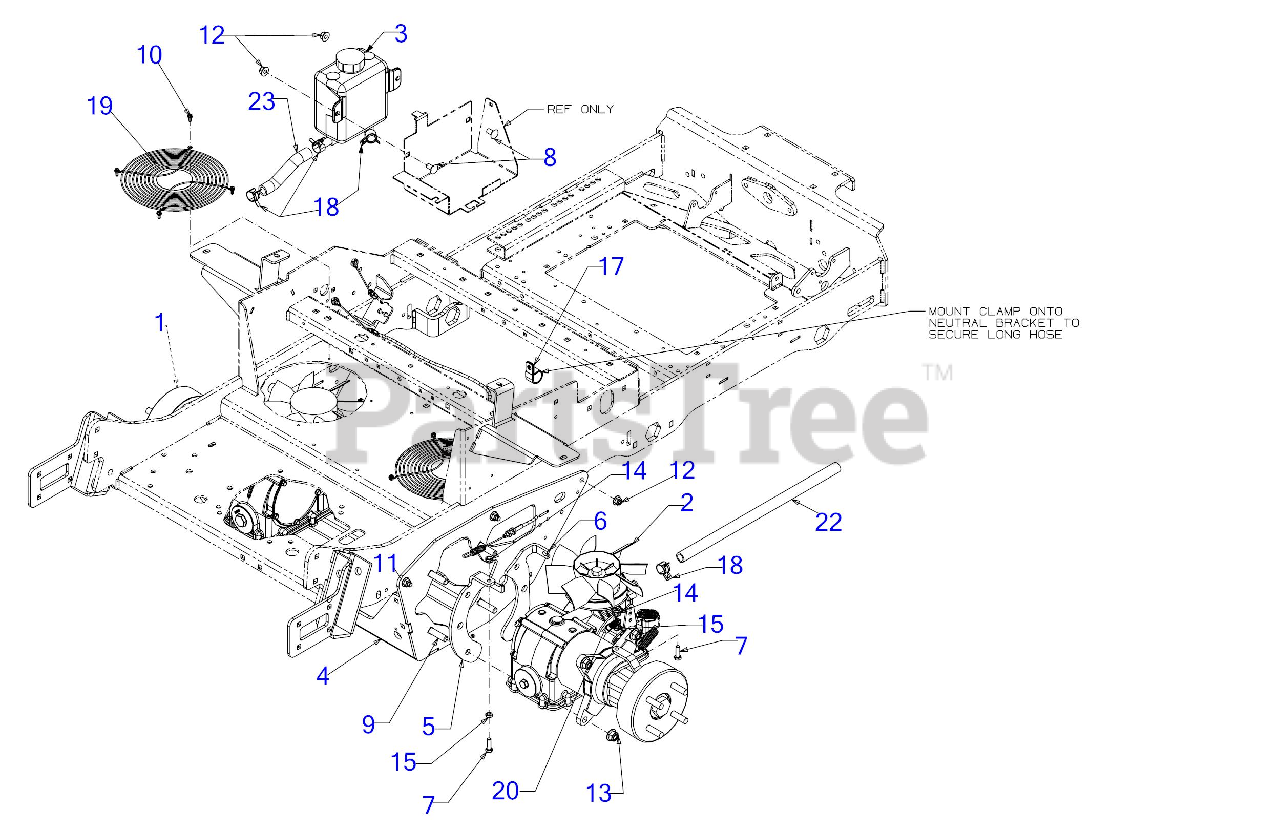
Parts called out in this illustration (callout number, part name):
1	TRANSMISSION/MOTOR ASSEMBLY (LH)(PARKER)
2	TRANSMISSION/MOTOR ASSEMBLY (RH)(PARKER)
3	HYDRO TANK ASSEMBLY
7	SCREW 5/16-18 x 1.0 GR5
8	CARRIAGE BOLT 3/8-16 x .750 GR5
9	CARRIAGE BOLT 1/2-13 GR5
10	SCREW 10-24 x 0.500
11	CARRIAGE BOLT 3/8-16 X1.25 GR5
14	HEX FLANGE NUT
17	HOSE CLAMP 1.0"
18	HOSE CLAMP
20	EXTENSION SPRING .500 OD x 1.71
22	OIL HOSE 5/8 ID X 18.00 LG
